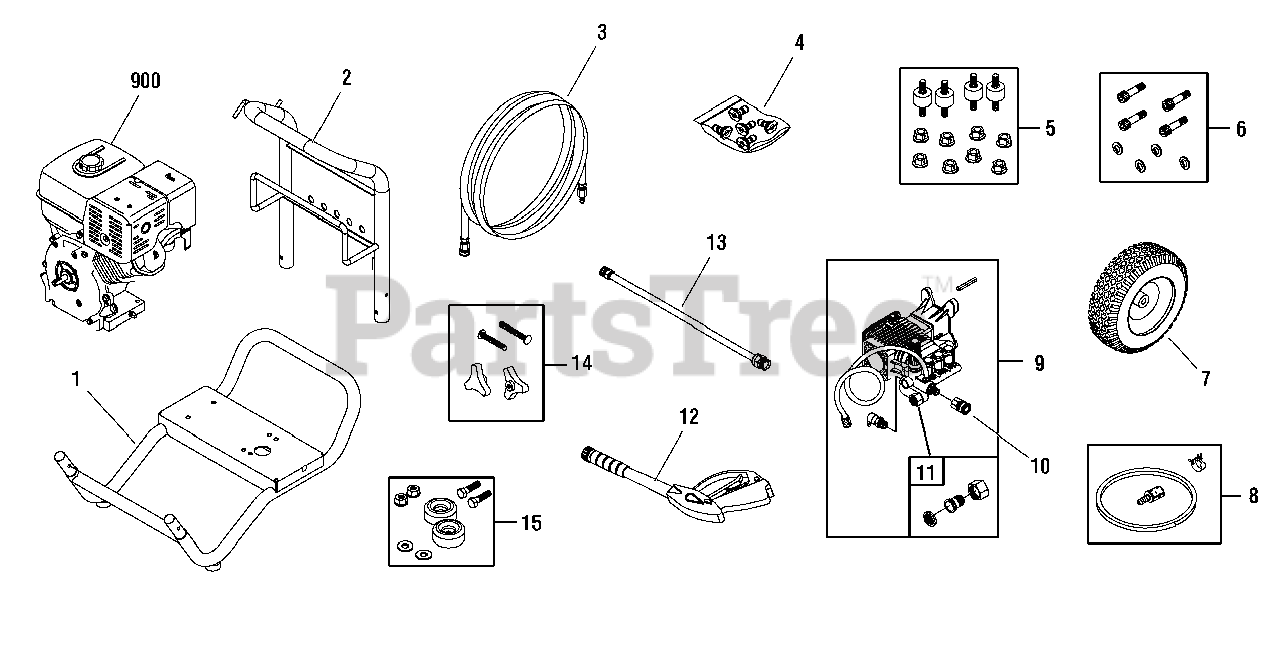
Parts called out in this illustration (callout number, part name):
4	KIT, QC Nozzles
5	KIT, Hardware, Engine Mounting
6	KIT, Hardware, Pump Mounting
9	PUMP
10	FITTING
11	ADAPTER, Garden Hose
12	GUN
13	EXTENSION, QC
14	KIT, Hardware Handle
15	KIT, Vibration Mount
900	* ENGINE
